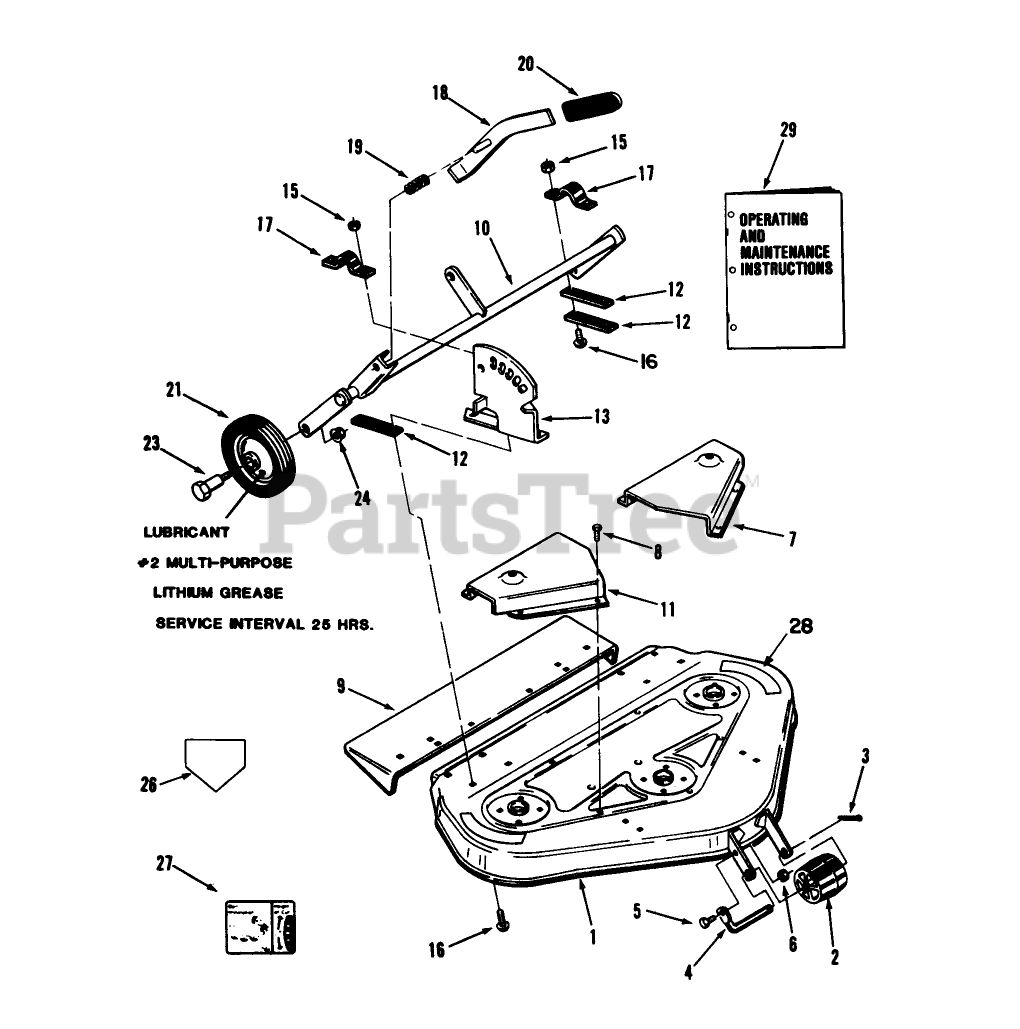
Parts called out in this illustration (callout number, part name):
1	Mower Deck
2	Roller
3	Cotter Pin
4	ROLLER-SHAFT
5	Bolt
6	Nut
7	Cover-Belt
8	SCREW -4
9	Chute Extension
10	Gage Wheel Support
11	Belt Cover RH
12	Bar
13	Quadrant
15	Nut
16	Bolt
18	Lever
19	SPRING-COMPRESSION
21	WHEEL
23	BOLT-SHOULDER
24	Nut
26	DECAL-DANGER
27	DECAL-HEIGHT & BELT
28	DECAL - DANGER
29	Manual-Operators
